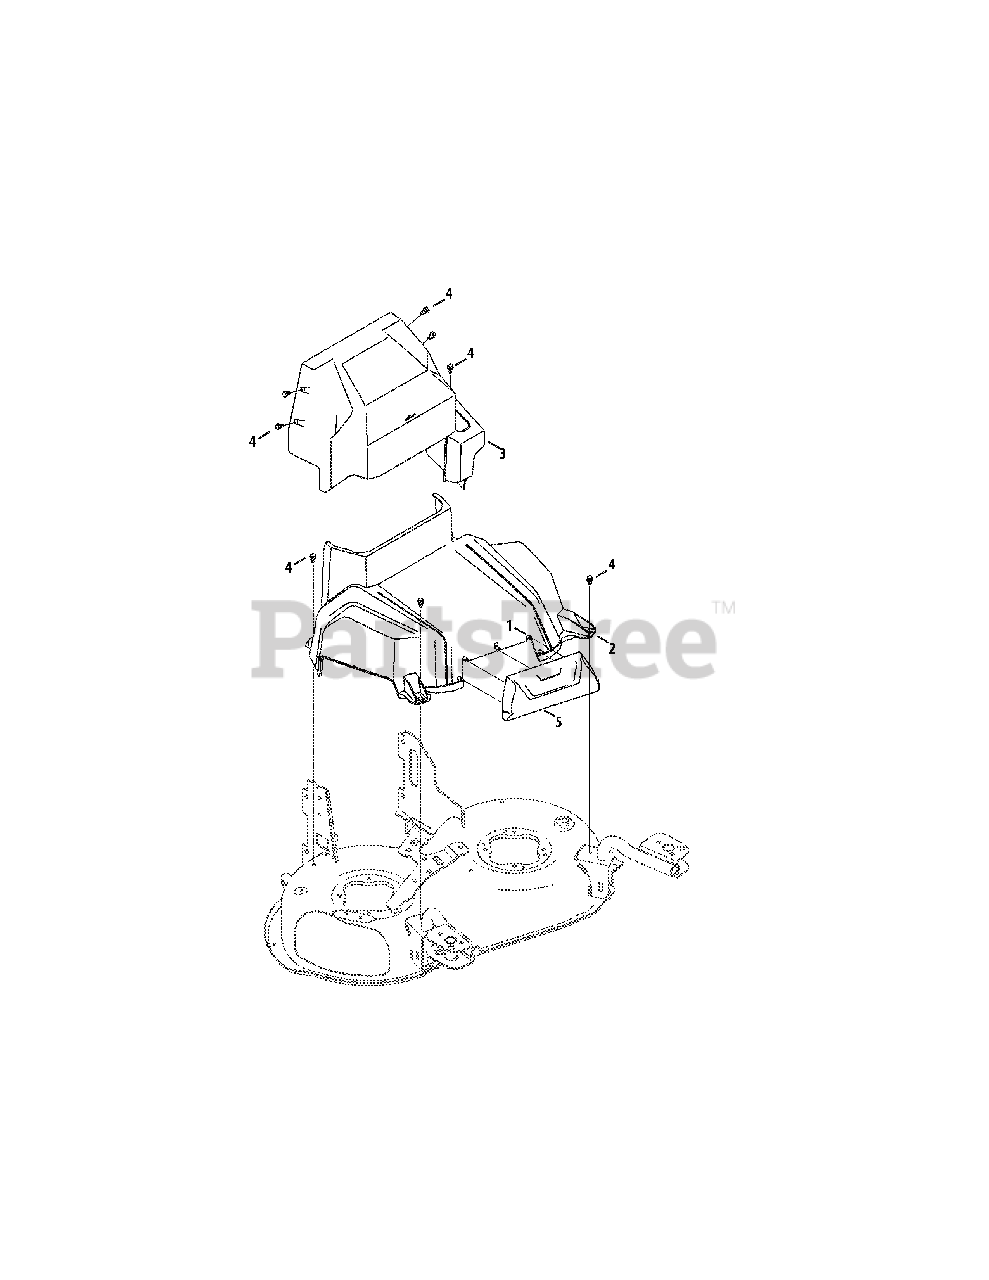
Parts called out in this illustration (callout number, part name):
1	Screw, 1/4-10 x .75
2	Deck Cover, Lower
3	Deck Cover, Upper
4	Shoulder Screw, 1/4-20 x 0.50
5	Lower Deck Cover
